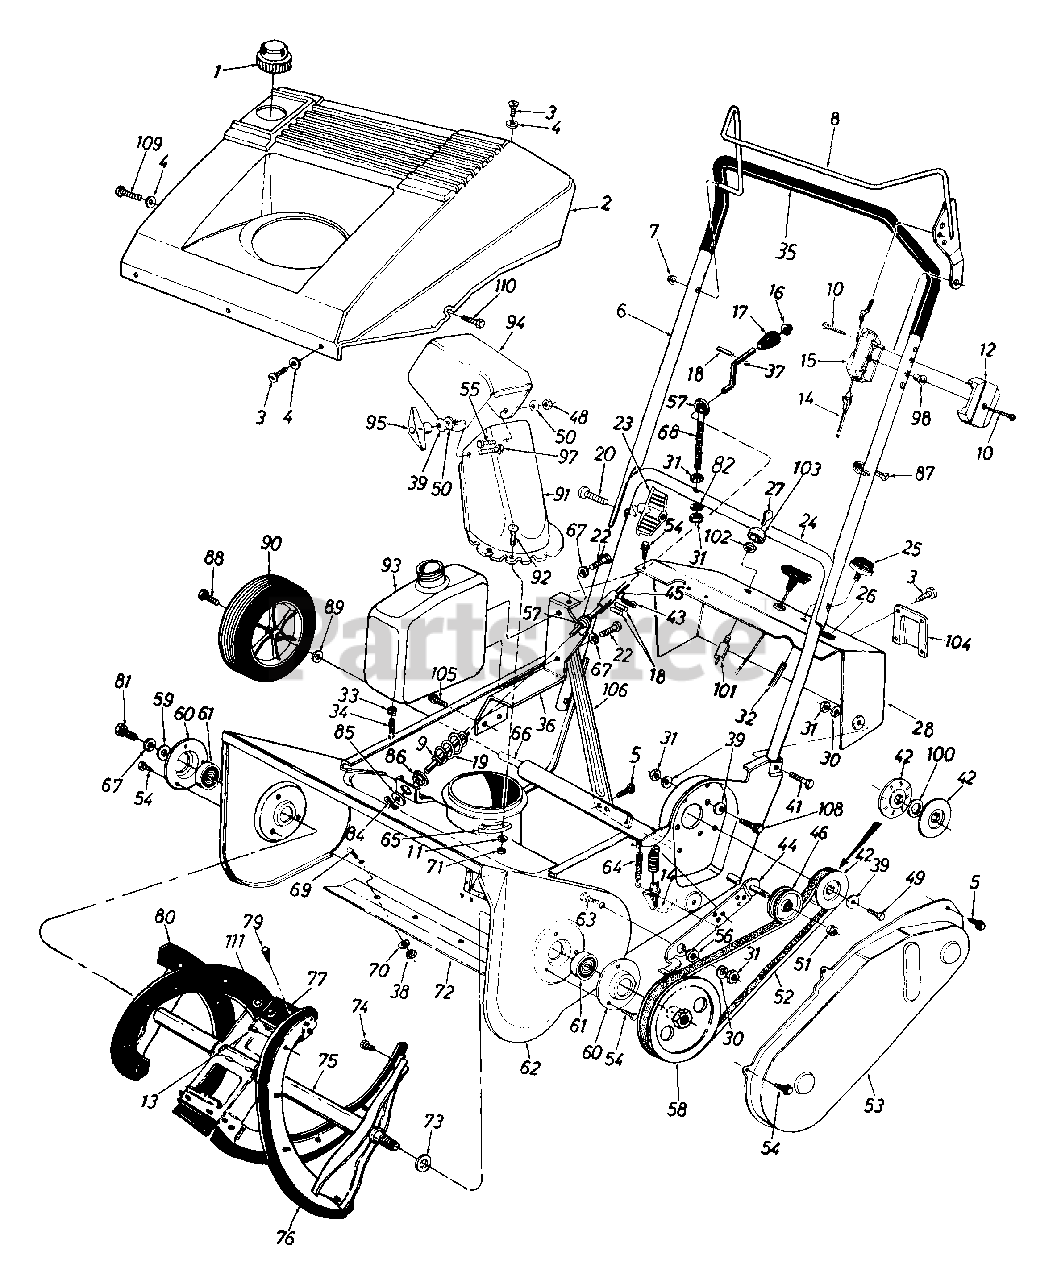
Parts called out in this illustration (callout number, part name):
1	Gas Tank Cap
2	Shroud
3	Hex B-Tap Scr. #10 x .38" Lg.
4	Fl-Wash. .203" I.D. x .41"
5	Hex L-Wash. Hd. AB-Tap 1/4 x .62" Lg.
8	Control Handle Ass'y.- L.H.
9	Fl-Wash. .385" I.D. x .62"
10	Truss Mach. Hi-B Tap Scr. #12 x 1.5" Lg.
11	Fl-Wash. .281" I.D. x .5" O.D.
12	Control Panel Half
13	Pop Rivet .187" Dia.
14	Clutch Cable 35" Lg.
15	Control Panel Half
16	Push Cap 3/8" Rod
17	Knob - 3/8" Dia. Hole
18	Roll Pin 1/8" Dia. x .63" Lg.
19	Lower Chute Crank Ass'y.
20	Curved Hd. Bolt 5/16-18 x 2" Lg.
22	Hex Bolt 1/4-20 x .5" Lg.
23	Handle Knob
24	Lower Handle
26	Plastic Plug
31	Hex Nut 5/16-18 Thd.
32	Primer Hose - 9" Lg.
33	Hose Clamp - 1/2" O.D.
34	Gas Line - 26" Lg.
35	Foam Grip 22" Lg.
36	Gas Tank Support Brkt.
37	Upper Chute Crank
38	Hex Jam Nut 1/4-20 Thd.
39	Bell-Wash. .345" I.D. x .88"
41	Hex Bolt 5/16-18 x 1.5" Lg.
42	3/8" "V"-Pulley Half .625" I.D. x 6.0" O.D.
43	Cotter Pin 3/32" Dia.
44	Idler Brake Brkt. Ass'y.
45	Spacer .38" I.D. x 1.12" Lg.
46	Fl-Idler w/Flanges 2.12" O.D.
48	Hex L-Nut 5/16-18 Thd.
49	Hex Bolt 5/16-24 x .75" Lg.
50	Fl-Wash. .344" I.D. x 1.25"
51	Hex Patch L-Nut 3/8-24 Thd.
52	V-Belt
54	Hex B-Tap Scr. 1/4" x .38" Lg.
55	Carriage Bolt 5/16-18 x .75"
56	Shld. Spacer .50" Dia. x .27"
57	Plastic Bushing.38" I.D.
58	1/2" "V"-Pulley 1/2-20 L.H. x 6"
59	Fl-Wash. 1/4" I.D. x .93" O.D.
60	Bearing Cup
61	Ball Bearing
64	Extension Spring 1.12" Lg.
65	Chute Flange Keeper
66	Wheel Axle 20.6" Lg.
67	L-Wash. 1/4" I.D.
68	Eyebolt
69	Carriage Bolt 1/4-20 x .50"
70	Fl-Wash. .281" I.D. x .73"
71	Hex L-Nut 1/4-20 Thd.
72	Shave Plate
73	Fl-Wash. .510" I.D. x 1.0" O.D.
74	Hex Wash. B-Tap Scr. 1/4 x .62" (Spec)
75	Auger Ass'y.
76	Rubber Spiral - L.H.
77	Rubber Paddle
79	Hex Wash. B-Tap Scr. #10 x .62" Lg.
80	Rubber Spiral - R.H.
81	Hex Wash. TT-Tap Cl-Scr. 1/4-20 x .75" Lg.
82	Saddle Wash. .32" I.D.
84	Cotter Pin 3/32" Dia. x .75"
85	Fl-Wash. .406" I.D. x 1.25"
86	Hex Bushing .385" I.D.
87	Cable Tie
88	Hex Tap Scr. 3/8-24 x .88" Lg.
89	Fl-Wash. .510" I.D. x .75"
90	7" Wheel & Tire Ass'y.
91	Lower Chute
92	Truss Mach. Scr. 1/4-20 x .75"
93	Fuel Tank - Two Qt.
94	Upper Chute
97	Carriage Bolt 5/16-18 x 1"
98	Control Disc Pin
100	Fl-Wash. .635" I.D. x .93" O.D. x .06"
101	Key Switch
102	Ignition Switch Nut 5/8-32 Thd.
103	Ignition Switch Cap
104	Choke Cover
105	Hex Wash. Hd. Tap Scr. 1/4-.5" Lg.
109	Hex B-Tap Scr. #10 x 1.25" Lg.
110	Hex Wash. Hd. Tap Scr. 1/4-20 x 1" Lg.
111	Torx AB-Tap Scr. 1/4 x .62" Lg.
